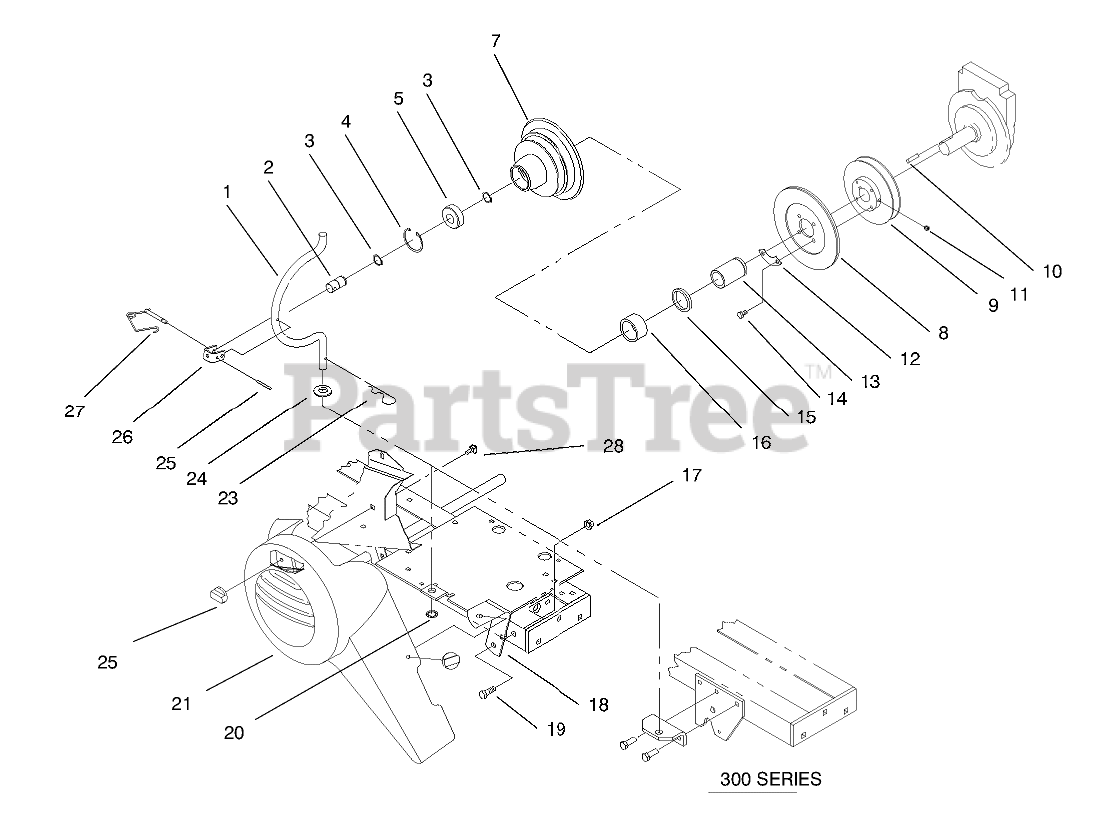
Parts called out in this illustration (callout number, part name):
1	ROD-HOUSING
2	SHAFT-PTO
3	Ring-Snap
4	RING-RETAINING
5	BEARING-BALL
7	Housing-Clutch
8	ASS'Y-CLUTCH PLATE
9	PULLEY
11	SCREW-SET, HSH
12	RETAINER
13	RACE-BEARING
14	SCREW-HEX HD CAP
15	SEAL-OIL
16	Seal
17	NUT-FLANGE
18	Bracket
19	SCREW-HH
20	RING-REINFORCED CIRC
21	GUARD - BELT
22	NUT - WING
23	PIN-COTTER, HAIR
24	WASHER-FLAT
26	CLEVIS
27	LOCKING PIN ASM
28	Retainer-Bolt
